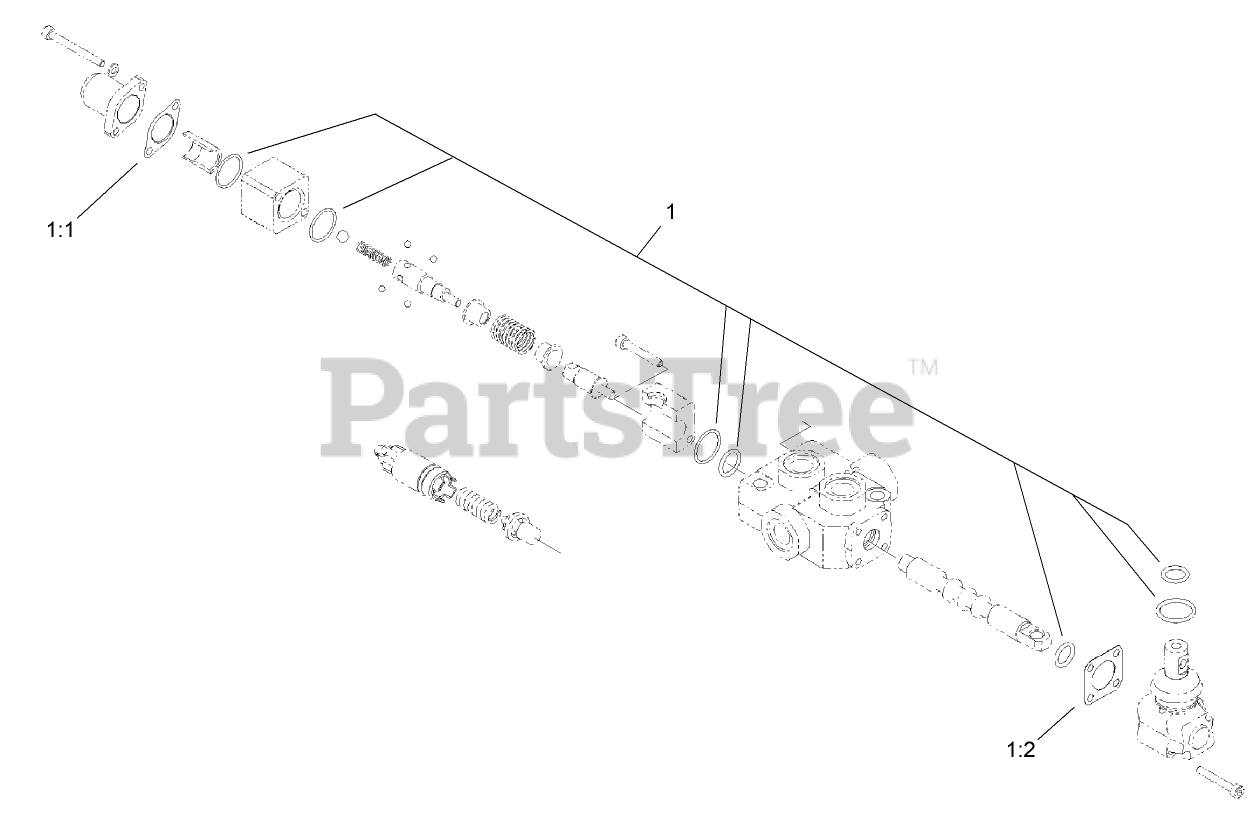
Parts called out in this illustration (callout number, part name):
1	SEAL KIT
1:1	GASKET
1:2	GASKET
